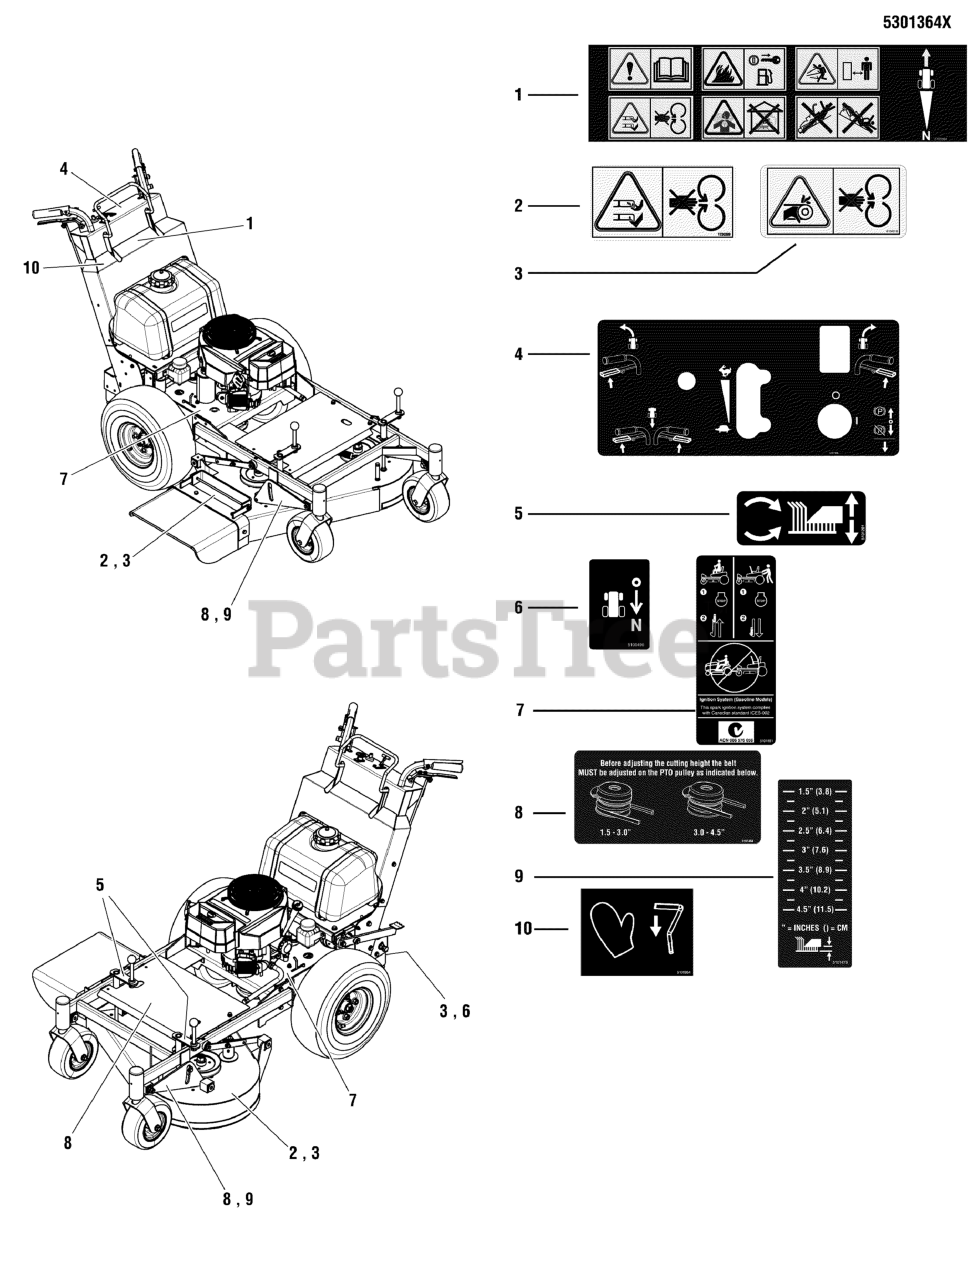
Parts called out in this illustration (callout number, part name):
1	DECAL, CCW, CE
2	DECAL-DANGER ROTATING BLADE SYMBOLS
3	DECAL, CE DANGER
4	DECAL, CONTROL PANEL, SPDD
5	DECAL, CUT HEIGHT, SPDD
6	DECAL, PEDAL
7	DECAL, TRANSAXLE RELEASE
8	DECAL, BELT LOCATION, PTO, SW20
9	DECAL, CUT HEIGHT, SW-20
10	DECAL, OPC, CCW
